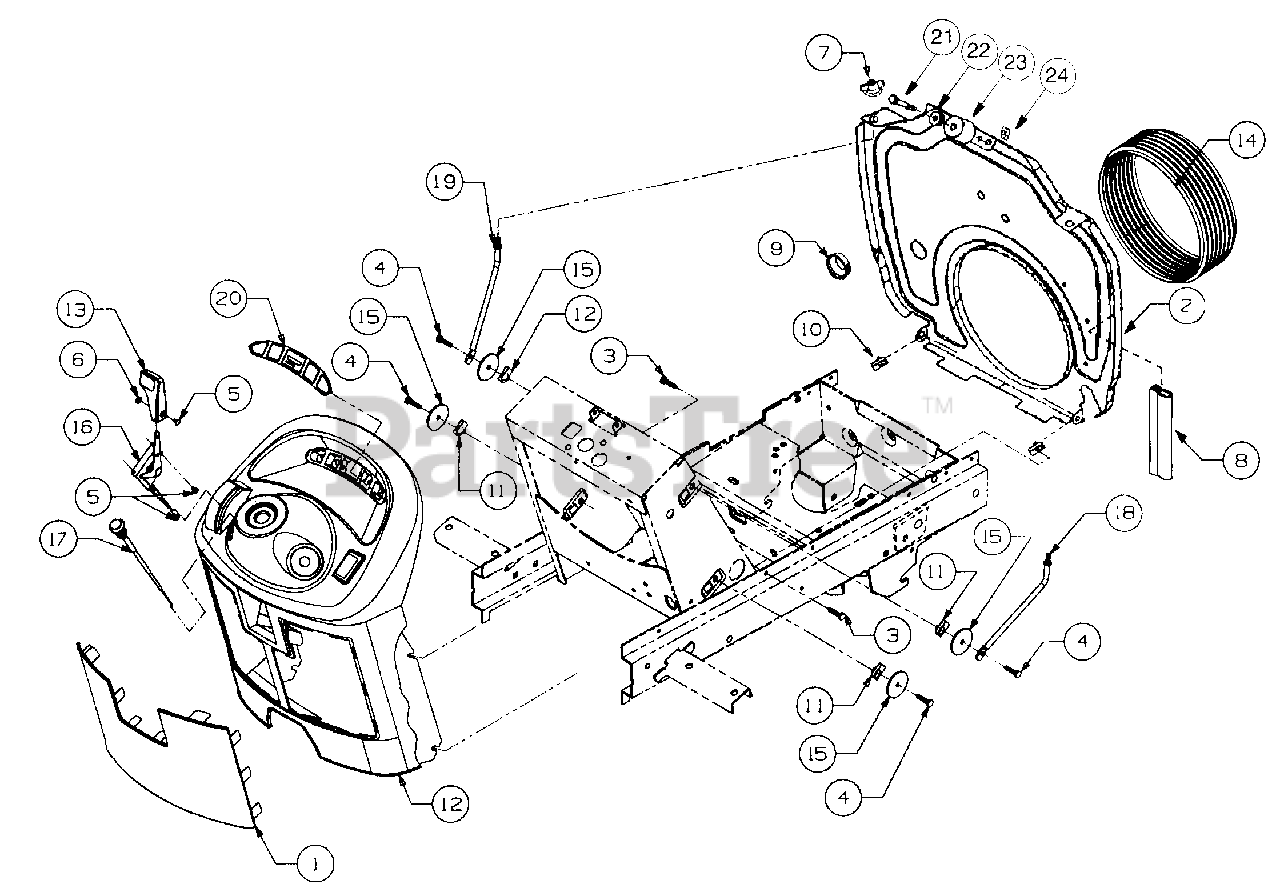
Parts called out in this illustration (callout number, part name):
2	Bulkhead, Lower
4	Screw, Hex Cap, 1/4-20 x 1.0
5	Screw, Cross Rec Truss Hd, #8-32 x .38
6	Nut, #8-32
7	Nut, Wing w/Bell Washer, 1/4-20
8	Seal, Push On Trim
9	Bushing, Snap, 7/8 ID
10	Nut, U-Type Speed, 1/4-20
11	Nut, U-Clip, 1/4-20
12	Panel Dash
13	Knob, Throttle
14	Boot, Intake
15	Washer, Flat, .285 x 1.75 x .10
16	Control, Throttle
17	Control, Choke
18	Rod, RH Mounting
19	Rod, LH Mounting
20	Label, Dash
21	Screw, Hex Cap,1/4-20 x 1.75 GR5
22	Washer, Flat, .283 x .75 x .030
23	Roller, Hood Latch
24	Nut, Hex Sems, 1/4-20
